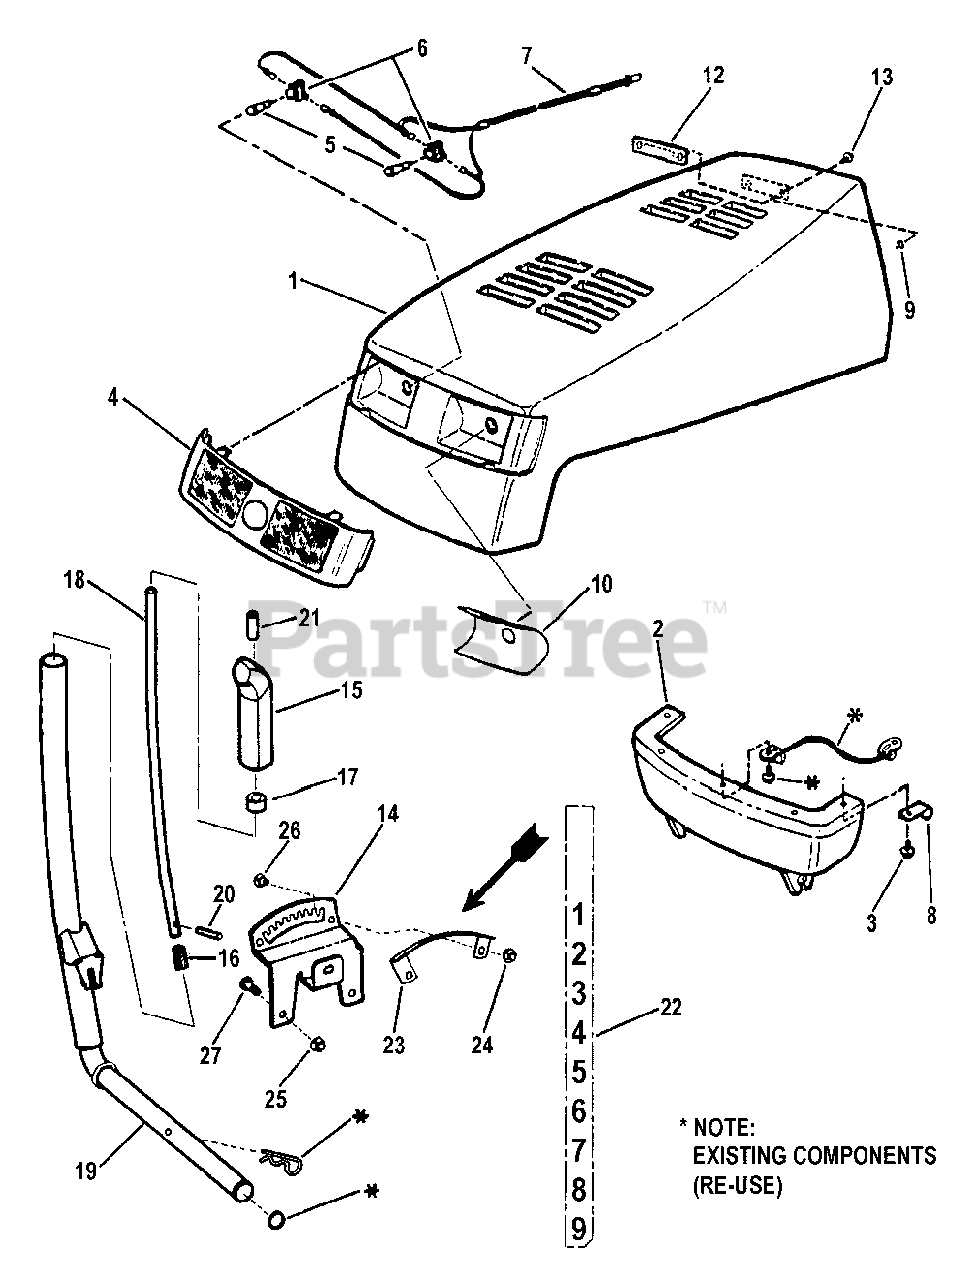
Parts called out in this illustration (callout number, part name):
1	HOOD, LT-Modified
2	SUPPORT, Hood
3	SCREW, M4.8 x 1.59 x 16.00mm Sems
4	LENS, Black Bezel
5	LAMP, 1141
6	SOCKET, Headlight (Snap-in)
7	HARNESS, Headlight Wiring (M & G Sockets)
8	CLIP, "J" (open type)
9	NUT, 1/4-20 Hex Nyloc
10	DECAL, R.H. Lens
11	DECAL, L.H. lens
12	LATCH, Spring
13	SCREW, 1/4-20 x 5/8" Truss Head Torx
14	QUADRANT, Lift
15	KNOB, Lift Handle
16	SPRING
17	PLUG, Nylon
18	ROD, Lift Lever
19	WELDMENT, Lift Handle
20	PIN, 3/16 x 2" Groove
21	CAP, Lift Rod
22	DECAL, Cut Height
23	INDICATOR, Cut Height
24	NUT, 1/4-20 Hex Flange Lock
25	NUT, 5/16-18 Hex Flange Lock, Grade 5
26	SCREW, 1/4-20 x 5/8" Flat Head Square Neck, Grade 2
27	SCREW, 5/16-18 x 7/8" Truss Head Torx
